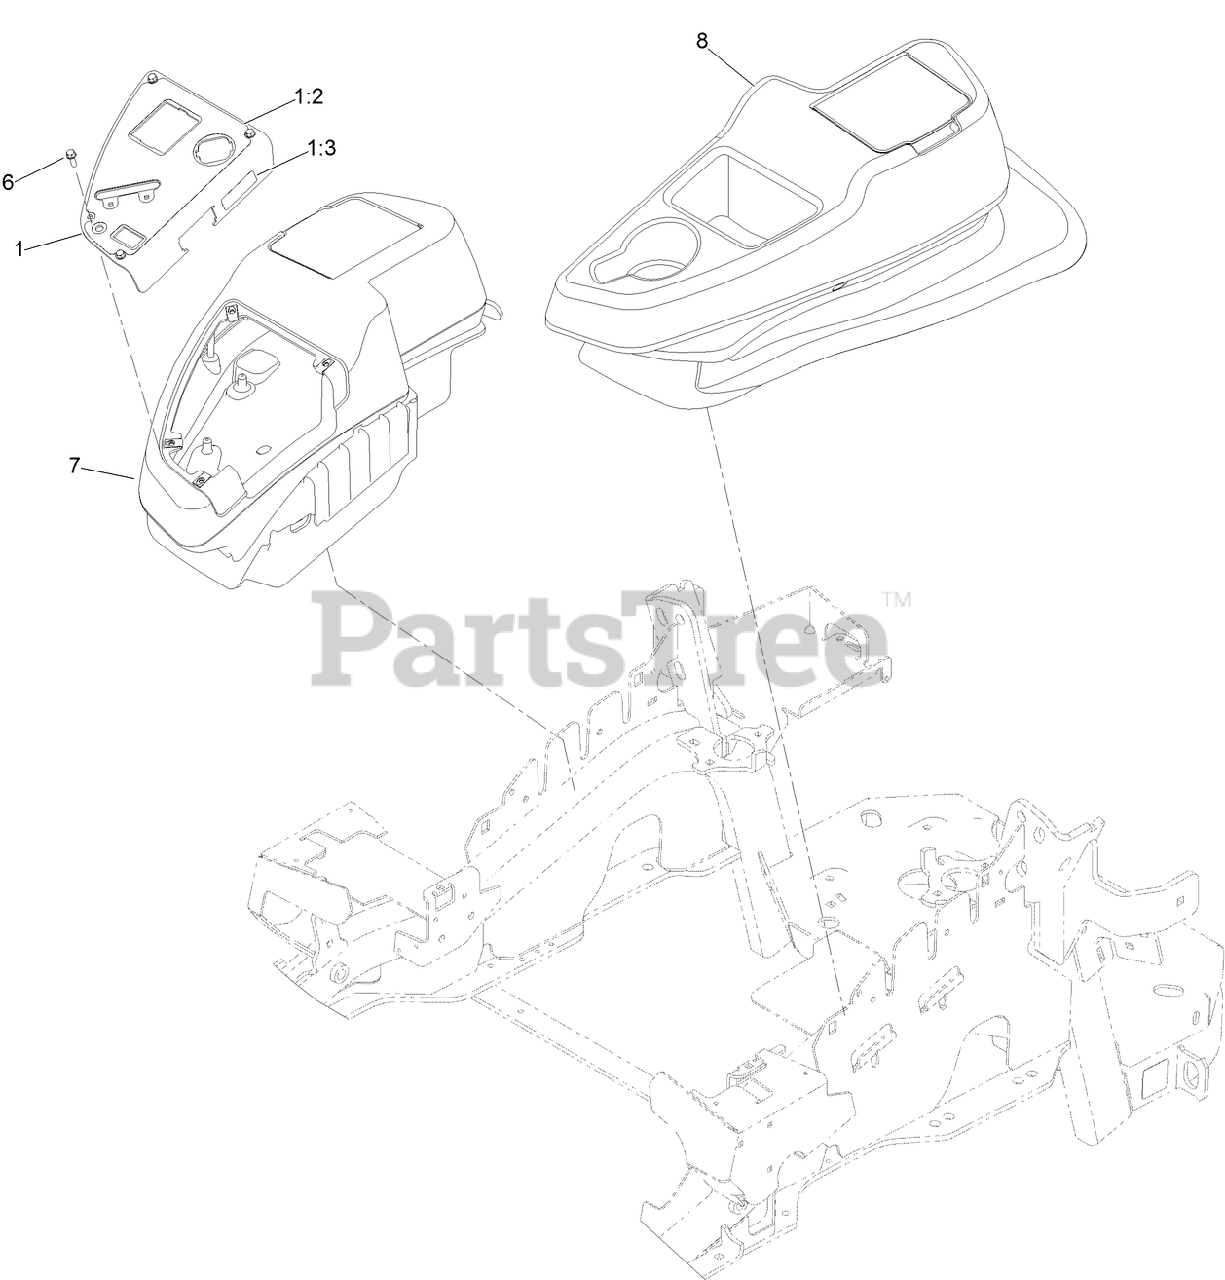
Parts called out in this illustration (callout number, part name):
1	CONTROL PANEL ASM
1:2	DECAL-PANEL, CONTROL
1:3	DECAL-FUSES
6	SCREW-HWH
7	RH CONSOLE ASM
8	LH CONSOLE ASM
